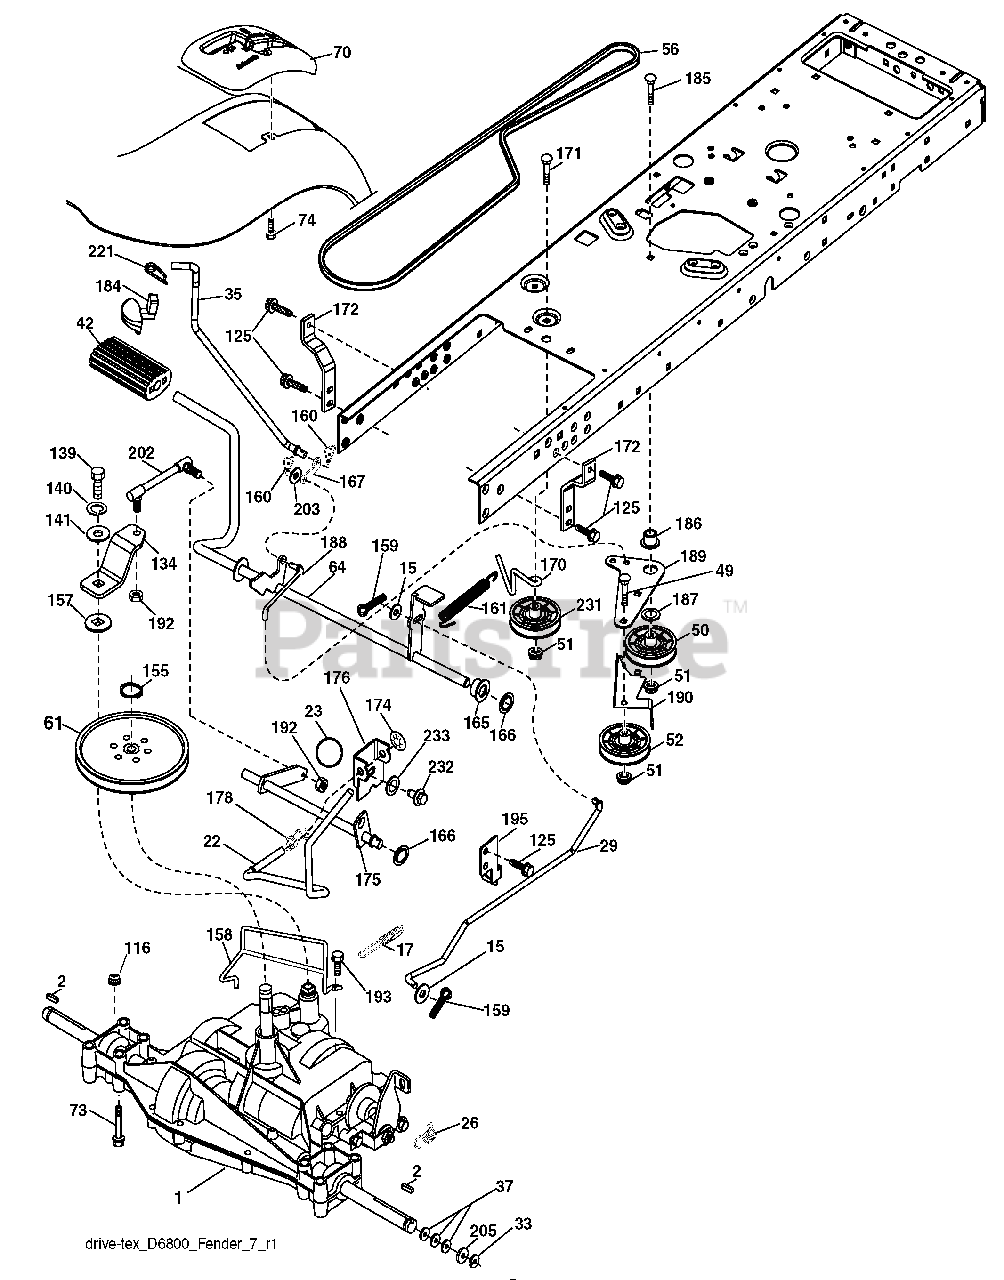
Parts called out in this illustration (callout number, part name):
1	Transaxle, D6800 (See Transaxle Breakdown)
2	Key Square
15	Washer 13/32 x 13/16 x 16 Ga.
17	Spring, Brake
22	Rod Shift
23	Knob
26	Spring Brake RTN
29	Rod, Brake
33	Ring E
35	Rod, Brake, Park
37	Washer 25/32 x 1-1/4 x 16 Ga.
42	Cover, Foot Pedal
49	Bolt
50	Pulley Idler Flat
51	Lock Nut 3/8-16
52	Idler V-Groove
56	V-Belt, Drive
61	Pulley Transaxle
64	Shaft Asm. Pedal Brake Control
70	Console
73	Bolt 5/16-18 Gr. 5
74	Screw 1/4 x 1/2
116	Nut Lock Hex Flange 5/16-18
125	Screw 5/16-18 x 3/4
134	Arm Shift
139	Bolt 1/4-20 unf Gr. 8 w/Patch
140	Washer Lock Hvy Helical 1/4
141	Washer 9/32 x 3/4 x 10 Ga.
155	Ring Retainer
157	Washer Plate Shf
158	Keeper T/A
159	Pin Cotter 1/8 x 3/4
160	Retainer Clip
161	Spring, Return, Clutch
165	Busing Shaft Brake Hand Control
166	Nut Push .625
167	Latch Brake Parking
170	Keeper Belt Centerspan
171	Bolt
172	Strap Torque LH
174	Nut Push
175	Shaft Asm Shift
176	Arm Clevis Rod Shift
178	Spring Shift
184	Handle Parking Brake
185	Bolt
186	Spacer Retainer
187	Washer
188	Link Clutch Ground Drive
189	Bellcrank Ground Drive
190	Keeper Bellcrank Ground Drive
192	Nut Lock Center 1/4-28
193	Screw 5/16-18 x 3/4
195	Bracket Brake Rod
202	Link Shift
203	Washer 11/32 x 11/16 x 16 Ga.
205	Washer 25/32 x 1-5/8 x 16 Ga.
221	Retainer Spring Clip Handle
231	Idler V- Groove
232	Bolt 7/16-14 x 1 Gr. 5
233	Washer Serrated
